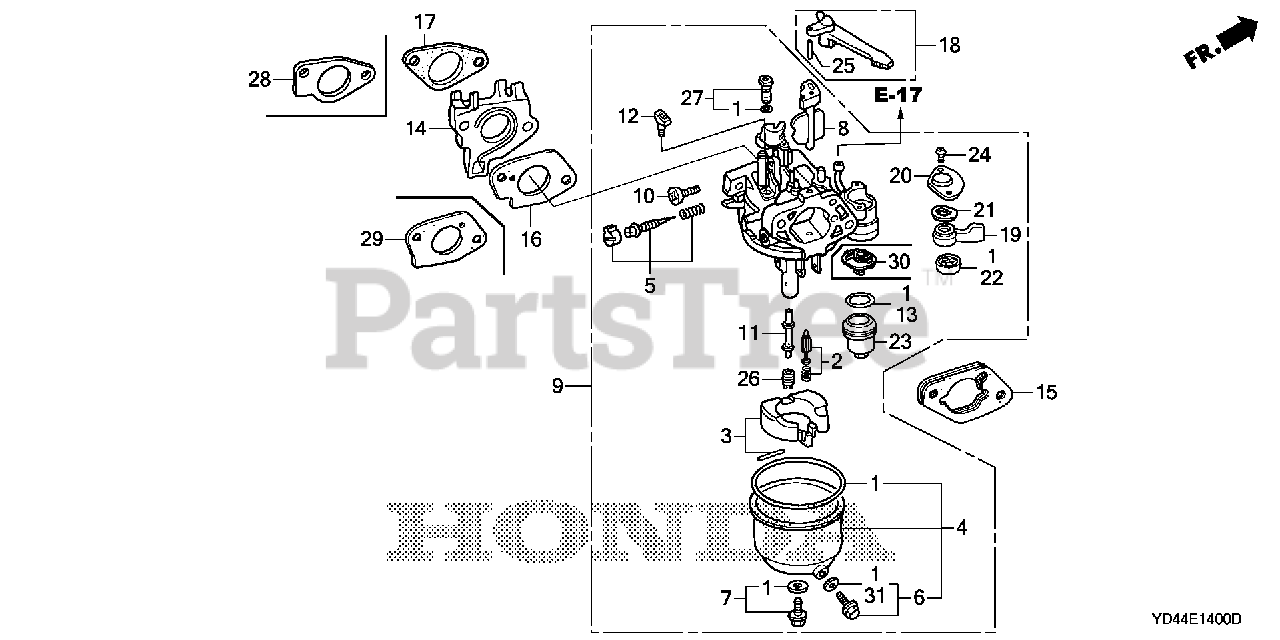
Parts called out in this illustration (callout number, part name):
1	GASKET SET (INCLUDE 16173-001-004) (INCLUDES 16173-001-004)
2	VALVE SET, FLOAT
3	FLOAT SET
4	CHAMBER SET, FLOAT
5	SCREW SET (Honda Code 4219879). (CARBURETOR NO.)
6	SCREW SET, DRAIN (Honda Code 1672187). (CARBURETOR NO.)
7	SCREW SET
8	CHOKE SET
9	CARBURETOR ASSY. (BE80B B)
10	SCREW, THROTTLE STOP
11	NOZZLE, MAIN (CARBURETOR NO.)
12	COLLAR, SET
13	GASKET, FUEL STRAINER CUP
14	INSULATOR, CARBURETOR
15	SPACER, CARBURETOR
16	GASKET, CARBURETOR
17	GASKET, INSULATOR
18	LEVER, CHOKE (STD)
19	LEVER, VALVE
20	PLATE, LEVER SETTING (CARBURETOR NO.)
21	SPRING, PETCOCK LEVER (CARBURETOR NO.)
22	GASKET, VALVE
23	CUP, FUEL STRAINER
24	SCREW, PAN (3X6)
25	PIN, SPRING (2X12)
26	JET, MAIN (#88) Use up to Engine SN BE81B B.
26	JET, MAIN (#90) Use from Engine SN BE81B C.
26	JET, MAIN (#92)
27	JET SET, PILOT (#35)
